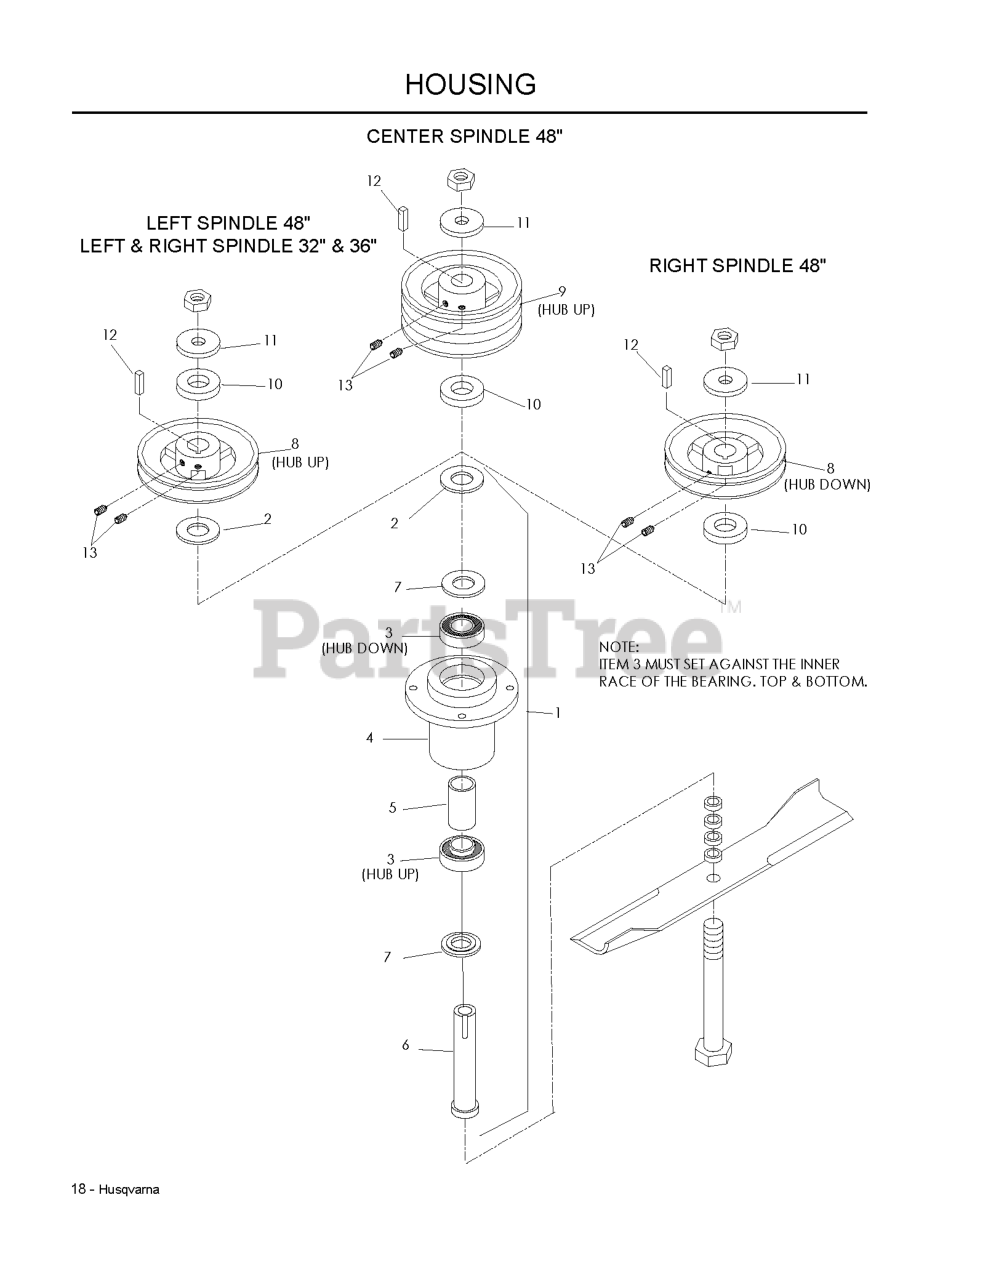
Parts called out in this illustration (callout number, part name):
1	HOUSING ASM
2	BEARING-ECC LOCK W/COLLAR
3	BEARING
6	SPINDLE SHAFT
7	COMBO SPACER
8	PULLEY W/SETSCREWS
9	PULLEY, DOUBLE W/SETS
11	WASHER, SUPPORT
12	KEY 1/4 SQ X 1 1/8
13	SET SCREW 5/16 NYLOC
